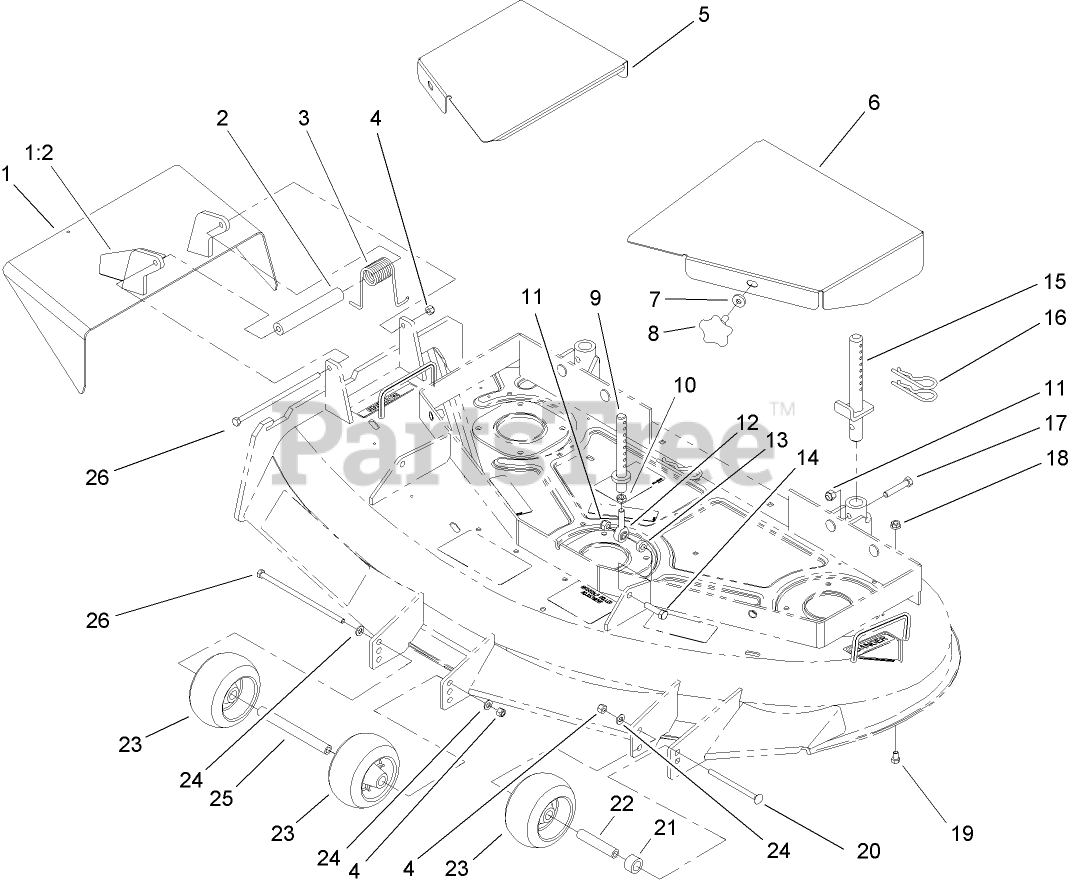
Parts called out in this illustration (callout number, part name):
1	Deflector ASM
1:2	DECAL-DANGER
2	SPACER
3	SPRING-TORSION
4	NUT-LOCK, NI
5	COVER-BELT, RH
6	COVER-BELT, LH
7	WASHER-RUBBER
9	FRONT PIN ASM
10	NUT-HJ
11	NUT-LOCK, NI
12	BALLJOINT
13	SPACER
14	SCREW-HH
15	REAR PIN ASM
16	PIN-HAIR
17	SCREW-HH
18	NUT-HF
19	SCREW-HH
20	SCREW-CARR
21	SPACER-WHEEL
22	BUSHING-ROLLER
23	WHEEL-GAGE
24	WASHER-PLAIN
25	SPACER-WHEEL
26	SCREW-HH
